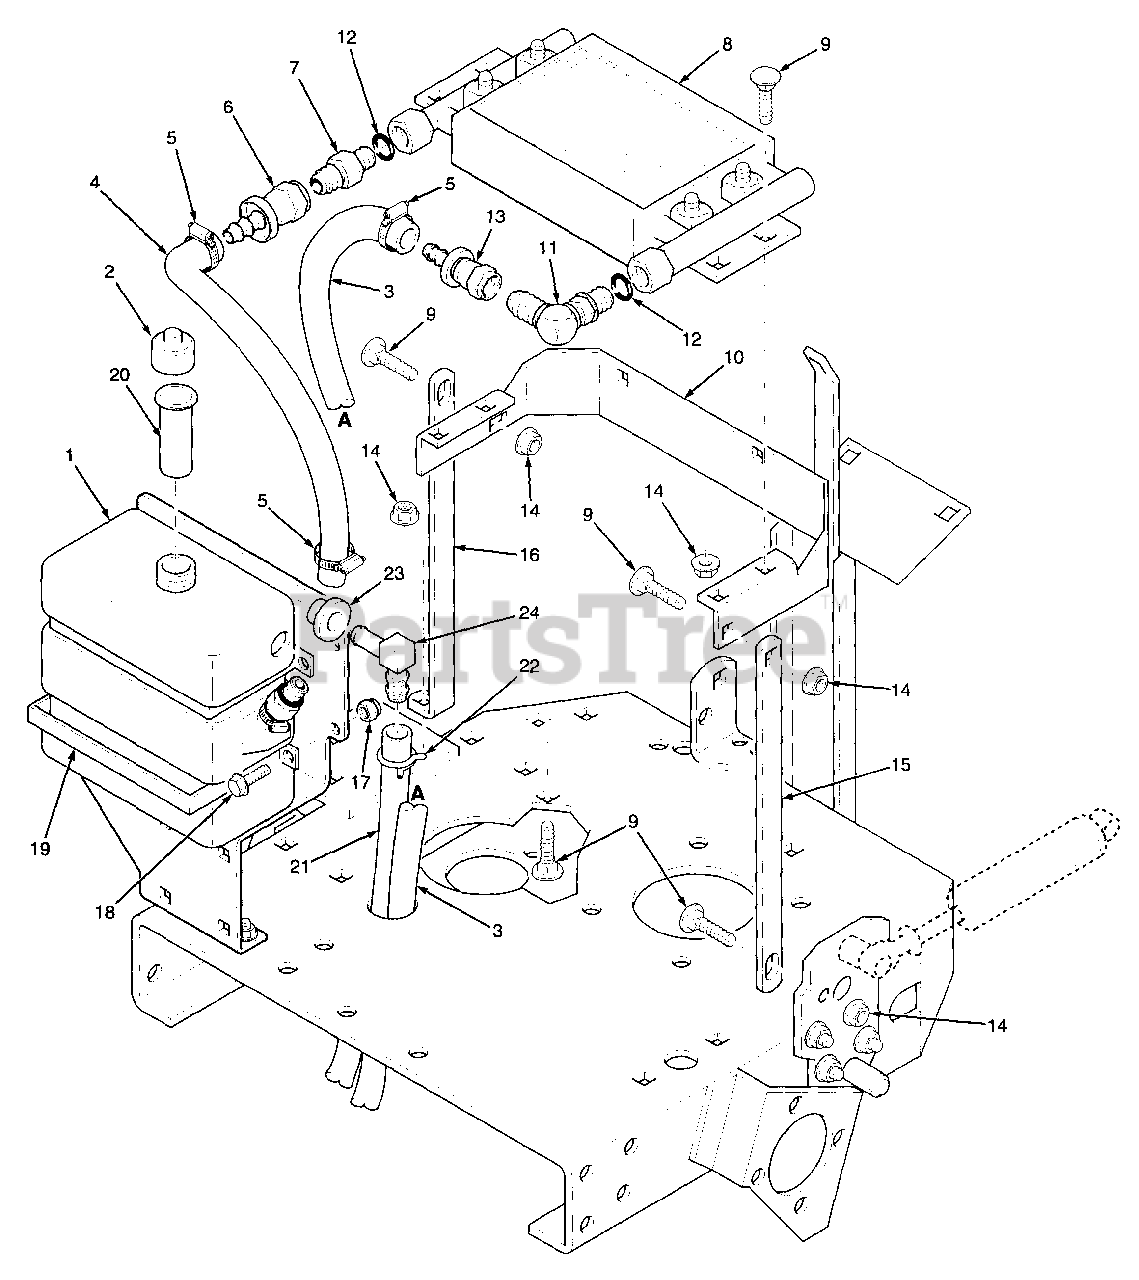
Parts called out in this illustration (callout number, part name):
1	Tank, Hydraulic
2	Cap, Hydraulic Tank
3	Hose, Pump to Oil Cooler
4	Hose, Oil Cooler to Tank
5	Clamp, Hose
6	Coupling, Flare Swivel
7	Tube, Union
8	Oil Cooler Assembly
9	Carriage Bolt, 5/16-18 x 3/4"
10	Bracket, Oil Cooler
11	Elbow, 90 Degrees
12	O-Ring
13	Coupling Flare Swivel
14	Serr. Fl. Hex Head Nut, 5/16-18
15	Brace, L.H. Cooler Support
16	Brace, R.H. Cooler Support
17	Elastic Stop Nut, 1/4-20
18	Serr. Fl. Hex Head CPSCR, 1/4-20 x 3/4"
19	Strap, Oil Tank
20	Filler Neck Insert
21	Hose, 1/4" Pushlock
23	Bushing
24	90 Degree Elbow
